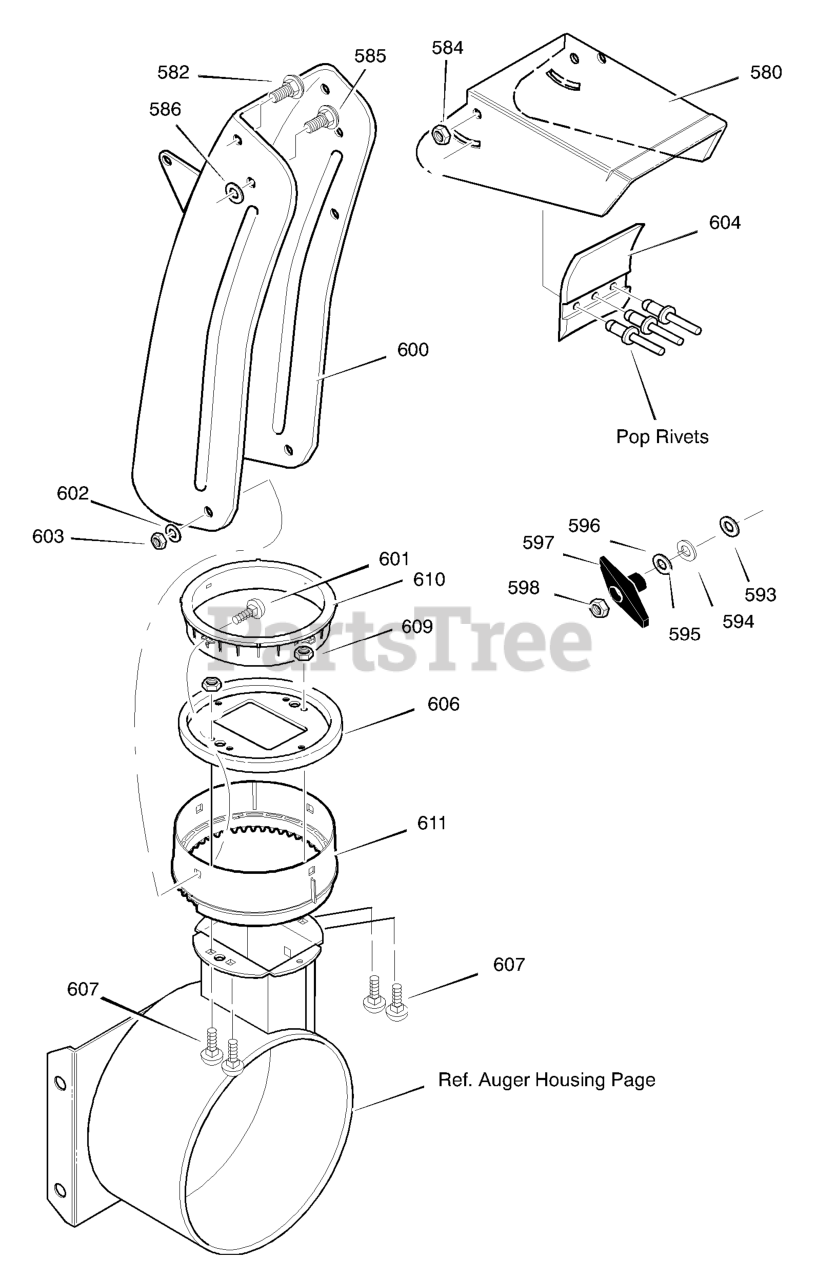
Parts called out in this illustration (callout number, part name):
580	CHUTE, UPPER W/REMOTE
582	SCREW, 5/16-18 x 0.75
584	NUT
585	SCREW, 5/16-18 x 0.75
593	WASHER, PLASTIC
594	WASHER, FLAT
595	WASHER, SPLIT
596	WASHER, FLAT
597	KNOB, T 3.00
598	NUT
600	CHUTE, LOWER / GUARD
602	WASHER, FLAT
603	NUT
606	CHUTE COLLAR
607	BOLT
609	NUT
610	RETAINER, RING INNER
611	RETAINER, RING OUTER
